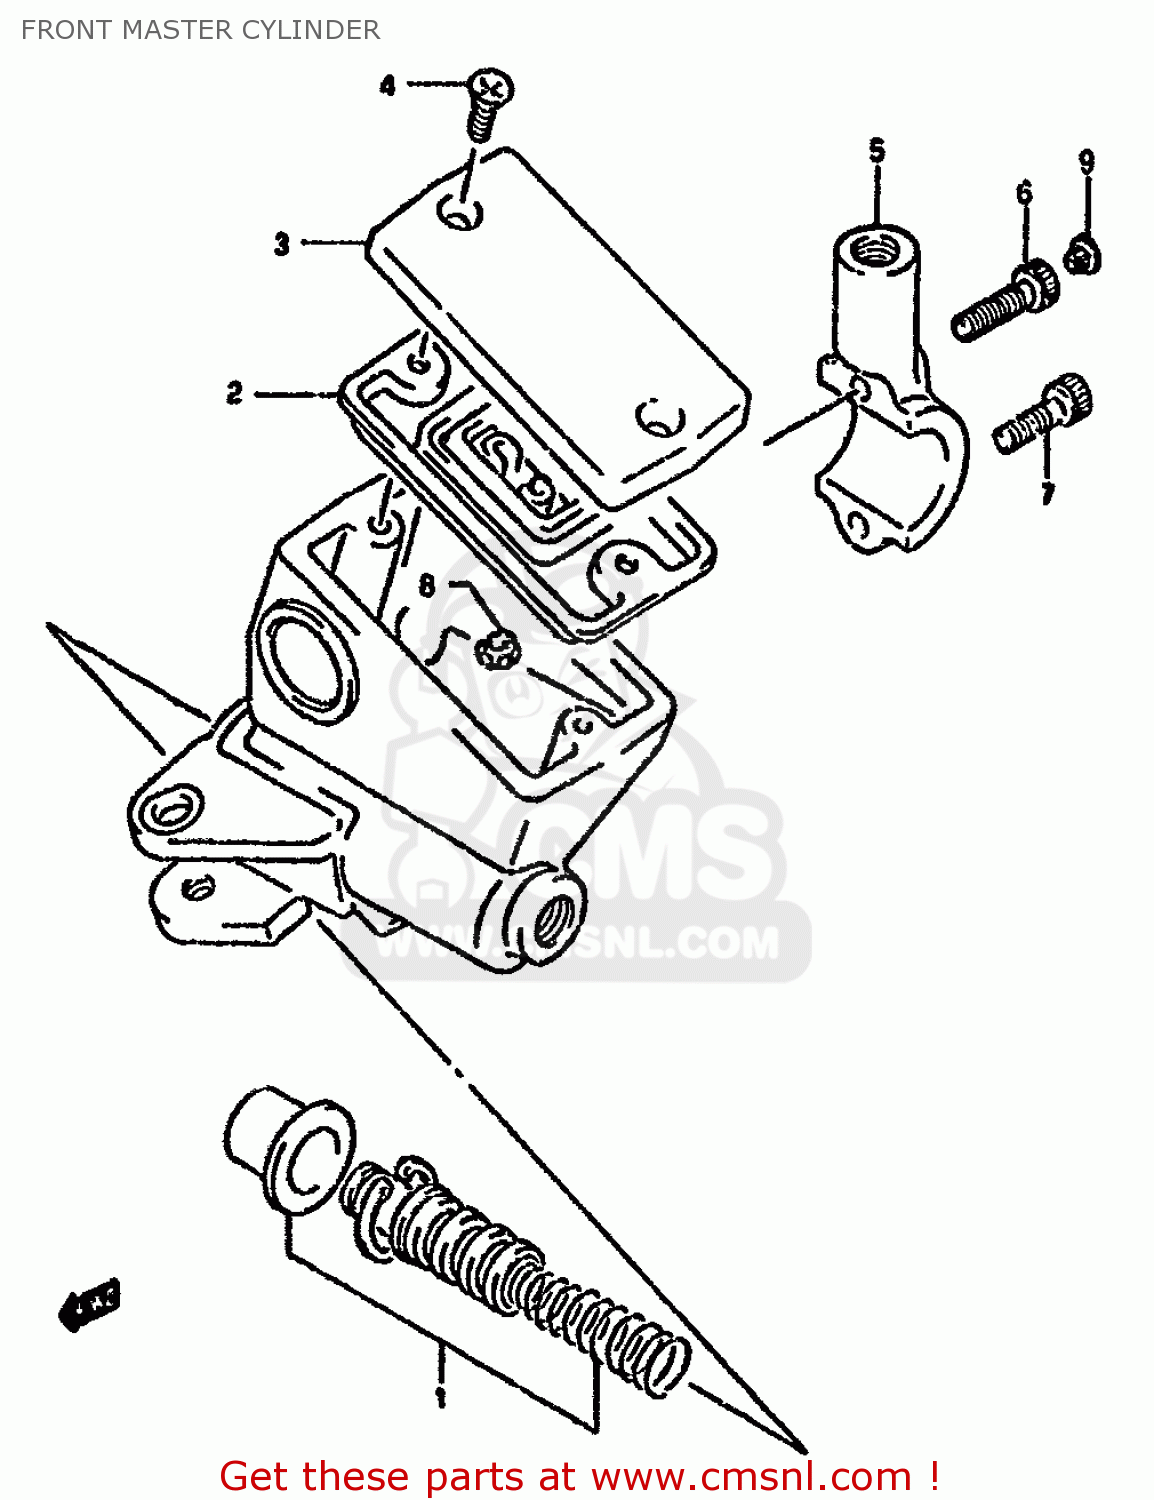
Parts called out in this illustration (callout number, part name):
1	PISTON & CUP SET
2	3
3	CAP
4	SCREW,RESERVOIR CAP
5	HOLDER
6	BOLT,UPPER
7	BOLT
8	PROTECTOR
9	CAP(OD:10)
